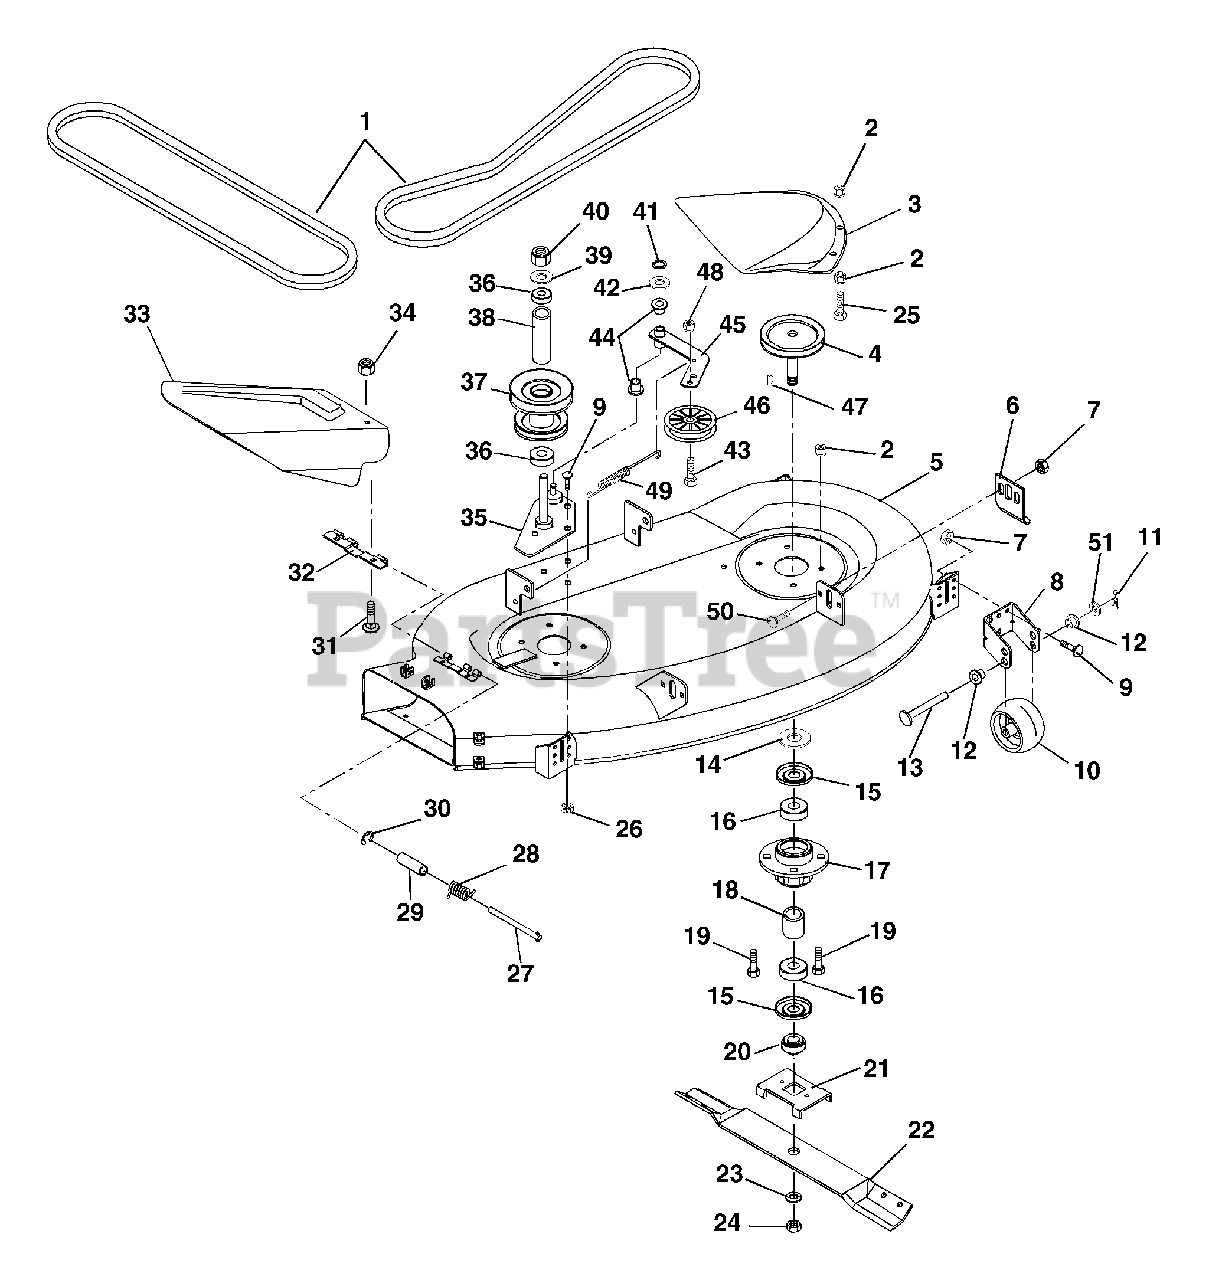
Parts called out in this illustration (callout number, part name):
1	V-BELT, 4L-RAW EDGE
2	@NUT-LK-TOP-FLG .38-16 YWZC
4	L. SPINDLE SHEAVE
4	R. SPINDLE SHEAVE
5	40" MOWER DECK W/DECALS
5	40" MOWER DECK ASSY COMPLETE
6	MOWER ADJUSTMENT TAB
7	@NUT-SPNLK-FLG .312-18 YWZC
8	CLEVIS
9	@BLT-RHDSSQNK .31-18X.62 G5YZ
11	PIN-HAIR INT .08X.18X1.18 YWZC
12	BSHG-FLG .372X.500X.312X.625NY
13	PIN-CLEV .371X3.25 YWZC
14	WSHR-FL-STL .755X1.25X.125 YZ
15	BEARING SLINGER
16	BRG-BALL .750X1.781X.61
17	SPINDLE HOUSING
18	SPACER .753X1.000X1.140
19	@BLT-RDHDSQNK .38-16X1.00 G5YZ
20	RETAINER HUB
21	BLADE TRAY 48
23	@WSHR-LK .75X.188 REG YWZC
24	NUT-JAM .75-10 YWZC
25	@BLT-HEX .38-16X1.00 GR5 YWZC
26	@NUT-SPNLK-FLG .312-18 YWZC
28	SG-TORS .095X.50X 1.0
29	BSHG-SLV .334 X .502 X 1.437
30	RG-RTNG-EXT .312X.025
31	BLT-RDHDSQSHNK.25-20X.50 YWZC
32	HINGE PLATE
33	40IN. CHUTE DEFLECTOR
34	@NUT-SPNLK-FLG .25-20 YWZC
35	MOUNT PLATE, 40"
36	BRG-BALL .625X1.375X.43
37	JACKSHAFT PULLEY
38	SPACER .640X.880X2.545
39	WSHR-FL-STL .630X1.005X.062 YZ
40	@NUT-LK-NYL .625-18 YWZC
41	RG-RTNG-EXT .500X.042 (E)
42	WSHR-FL-STL .505X.880X.072 YWZ
43	@BLT-HEX .38-16X1.50 GR5 YWZC
44	BSHG-FLG.500X.625X.312X.750NY
45	IDLER ARM
46	IDLER-FLAT 3.00X.38
47	KEY-WDRF .188X.625X.31 SAE9MOD
48	@NUT-SPNLK-FLG .375-16 YWZC
49	SG-TENS .113X.812X7.00
50	@BLT-RDHDSQNK .31-18X.75 G5YZ
51	WSHR-PLASTIC .390X.875X.062
